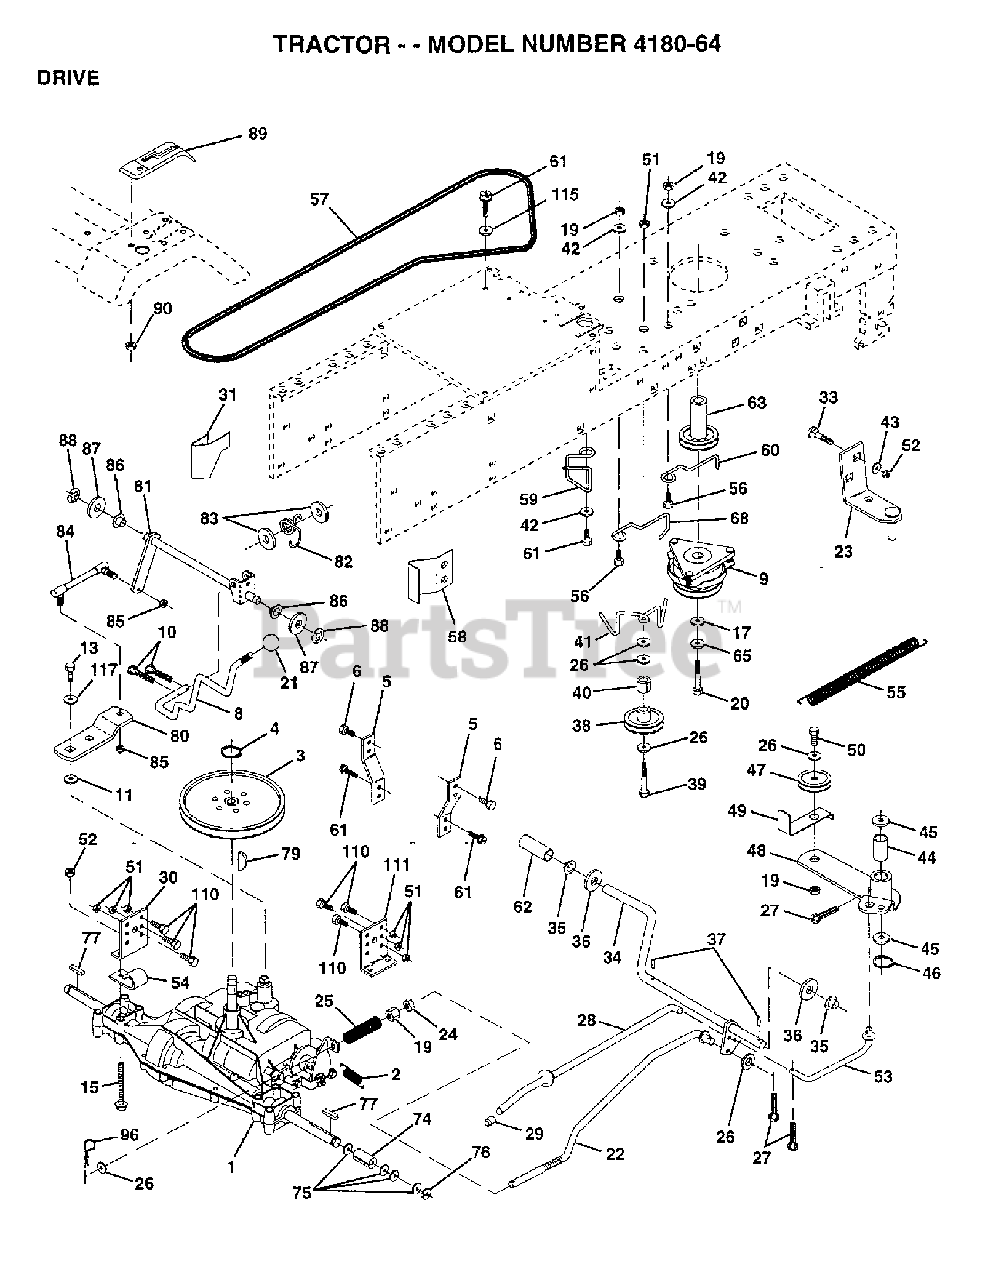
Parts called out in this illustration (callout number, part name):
2	SPRING T
3	PULLEY TRANSAXLE
5	Screw, Lt
10	PIN COTTER
11	WASH-SHFT PLT LT
15	BOLT HEX 5/16-18 GR 5
19	NUT
20	BOLT
21	KNOB T (1/2-HOLE)
22	ROD.ASM.BK.44.MWR (NLAD)
23	BRACKET ASM MTG
24	NUT
25	SPRING,ROD BRAKE
27	COTTER PIN
29	PLUNGER CAP
30	BRKT TRANS LH
31	KEEPER BELT LH
33	BOLT
35	BEARING.NYLON
36	WASHER LT
37	Drive Pin, 3/16 X 1"
38	FLAT IDLER PULLEY
40	SPACER T
42	WASHER
43	WASHER T
44	BEARING LT (2 2)
45	WASHER LT
46	KLIP RING
47	Idler Pulley
49	RETAIN BELT
50	Hex Bolt
51	LOCKNUT
52	LOCKNUT
54	CLIP,INSULATOR
55	SPRING, RETURN LT
57	BELT.GROUND.DRIVE
58	KEEPER,BELT RH
62	PEDAL COVER
63	ENGINE PULLEY
65	LOCKWASHER
68	KEEPER,BLT ENG LT
74	SPACER HYT
76	E RING HYT
79	KEY.WOODRUFF
80	ARM,SHIFT
81	SHAFT,SHIFTER
82	SPRING,TORSION
83	WASHER
85	NUT LOCK CENTER 1/4 -28 FNTHD
86	BUSHING.STEERING.ROD
87	WASHER D
88	KLIP RING
90	NUT.PUSH.3/16
96	RETAINER M
111	BRKT TRANS RH
115	WASHER GT
117	WASHER PM
